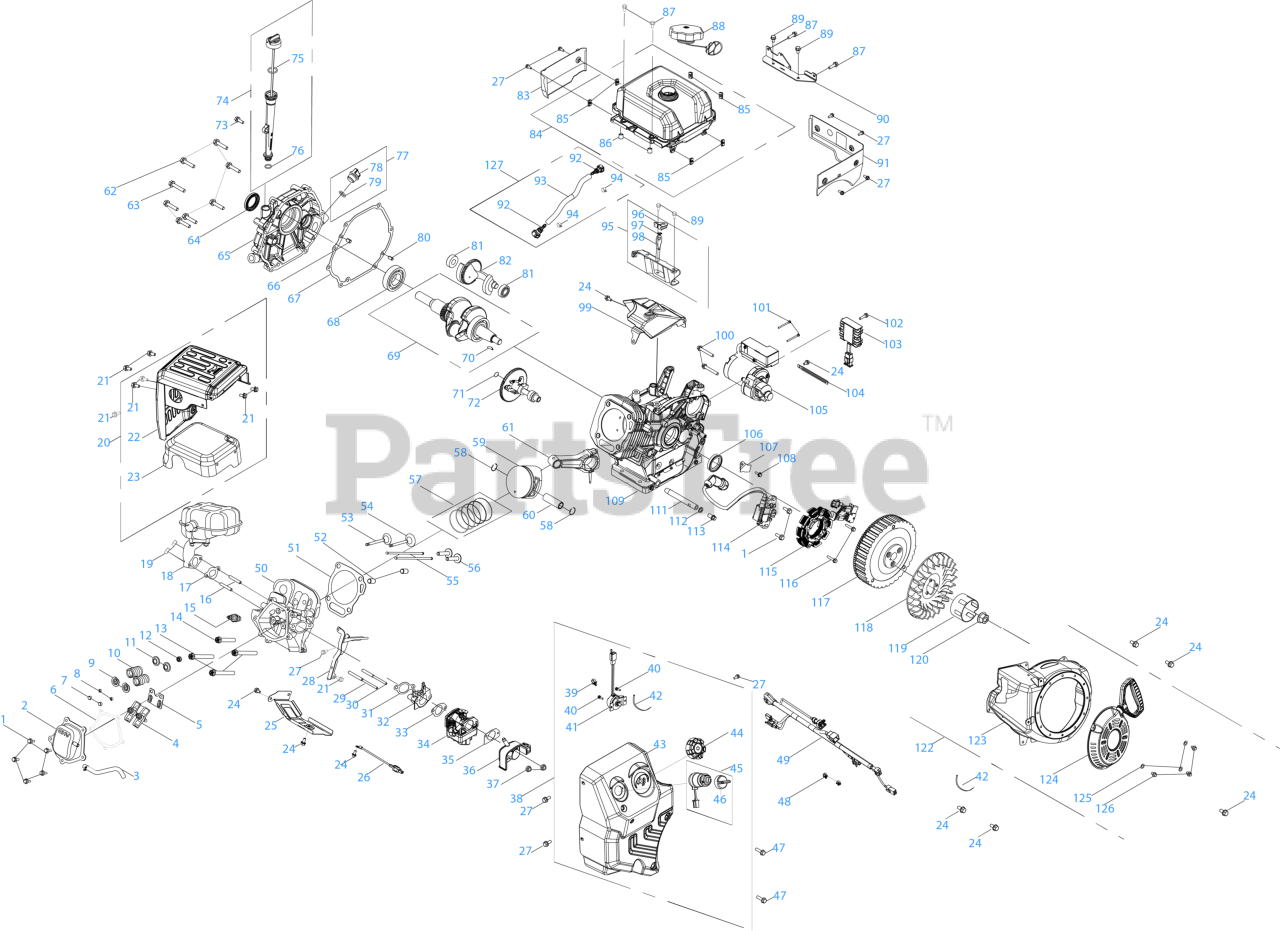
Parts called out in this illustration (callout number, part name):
1	BOLT M6 x 16
2	VALVE COVER
3	BREATHER HOSE
4	ROCKER ARM ASSEMBLY
5	PUSH ROD GUIDE
6	VALVE COVER GASKET
7	EXHAUST VALVE ADJUSTER
8	VALVE CAP
9	VALVE SPRING SEAT
10	VALVE SPRING
11	VALVE SPRING RETAINER
12	INTAKE VALVE SEAL
13	SCREW M10-1.25 x 87 x GR10.9
14	SCREW M10-1.25 x 65 x GR10.9
16	STUDS M8-1.25 x 48.5
17	MUFFLER GASKET
18	MUFFLER
20	MUFFLER SHIELD
21	BOLT M6-1 x 10 GR8.8
22	MUFFLER SHIELD (OUTER)
23	INNER MUFFLER SHIELD
24	BOLT M6-1 x 12 GR8.8
25	CYLINDER BAFFLE
26	TEMP SENSOR
27	BOLT M6-1 x 14 GR8.8
28	RECOIL SNOW GUARD
29	STUD M6 x 123
30	STUD M6-1 x 104
31	CARBURETOR INSULATOR GASKET
33	CARB GASKET
34	FUEL INJECTOR
35	AIR FILTER GASKET
36	HEATER BOX
38	CONTROL PANEL
39	PLASTIC SUPPORT CLAMP
41	SPEED CONTROL SWITCH
42	CABLE TIE - 3 x 150
43	CONTROL PANEL
44	SPEED CONTROL KNOB
45	KEY SWITCH
46	KEY SWITCH
47	SCREW M6-1 x 20 CL5.8
48	PLASTIC SUPPORT CLAMP
49	EFI ENGINE HARNESS
50	CYLINDER HEAD (690-WU) ZS
51	CYLINDER HEAD GASKET
53	EXHAUST VALVE
54	INTAKE VALVE
55	PUSH ROD
56	TAPPET
57	PISTON RING KIT
58	PISTON PIN SNAP RING
60	PISTON PIN
61	CONNECTING ROD ASSEMBLY
62	SCREW M8-1.25 x 38 GR10.9
63	BOLT M8 x 45
64	OIL SEAL
65	CRANKCASE COVER
67	CRANKCASE COVER GASKET
68	BALL BEARING
69	CRANKSHAFT ASSEMBLY
70	WOODRUFF KEY
72	ENGINE CAMSHAFT ASSEMBLY
73	BOLT M6-1 x 18 GR8.8
74	OIL DIPSTICK ASSEMBLY
75	DIPSTICK O-RING
77	OIL DRAIN PLUG ASSEMBLY
78	OIL PLUG
80	DOWEL PIN
81	BALL BEARING
82	BALANCE GEAR ASSEMBLY
83	FUEL TANK BACK PANEL
85	THREADED TAB
89	BOLT M8-1.25 x 14 GR8.8
90	FUEL TANK BASE BRACKET
91	FUEL TANK FRONT PANEL
92	QUICK DISCONNECT FUEL LINE
93	FUEL HOSE 8 x 14 x 290
95	FUEL TANK MOUNTING BRACKET
96	RUBBER GROMMET
97	RUBBER GROMMET
98	FUEL TANK MOUNTING BRACKET
99	GOVERNOR GEAR BRACKET
100	BOLT M8-1.25 x 55 GR8.8
102	BOLT M6-1 x 25 GR8.8
104	SUPPORT CLAMP
105	ELECTRIC STARTER
106	OIL SEAL
107	ALTERNATOR WIRE CLAMP BRACKET
108	BOLT M6-1 x 8 GR8.8
111	OIL DRAIN PIPE
112	FLAT WASHER
113	OIL DRAIN PLUG
114	IGNITION COIL
115	CHARGING COIL
116	BOLT-M6-1 x 30 GR8.8
118	COOLING FAN
119	STARTER CUP
120	FLYWHEEL NUT M16X1.5
122	RECOIL START
123	BLOWER HOUSING
124	RECOIL ASSEMBLY
125	RECOIL FLAT WASHER
126	BOLT M6 x 10
127	FUEL LINE ASSEMBLY
